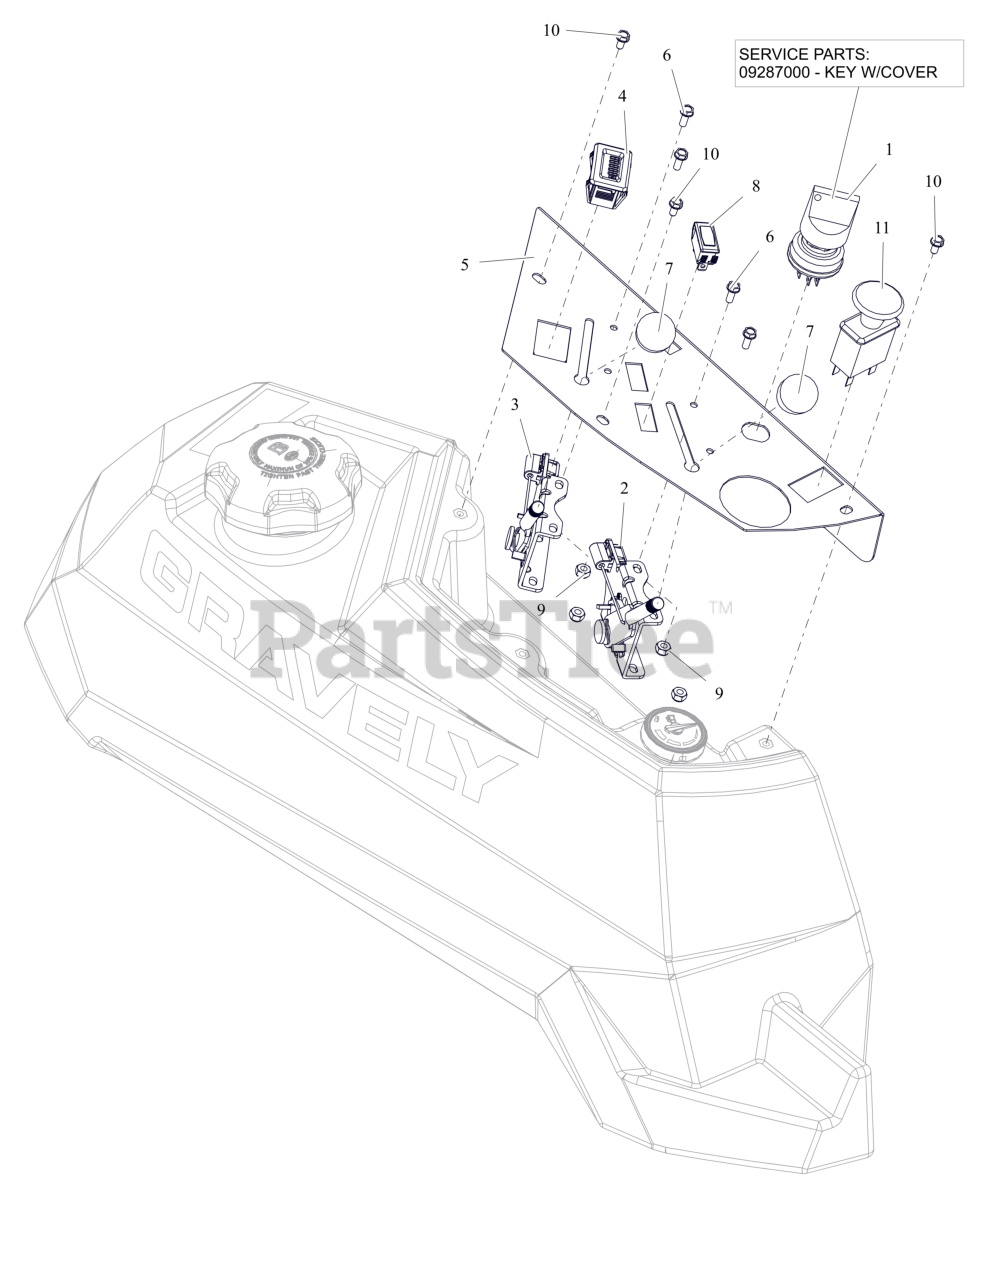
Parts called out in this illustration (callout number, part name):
1	SWITCH, IGNITION
1	KEY, W/ SHIELD
2	CABLE, PRO-CTRL 35.50"
3	CABLE, PRO-CONTROL 31.50"
4	HOUR METER
5	PT100 CONTROL PANEL - RED
6	BLT, HWH #10-24X.50 ZCC
7	KNOB-CONTROL-BLACK .38-16X.50
8	LIGHT, INDICATOR (RED)
9	NUT-LK-NYL #10-24 G2 ZCC
10	SCR-MCH 10-24X.38 HWHSTAINLESS
11	SWITCH, CLUTCH
